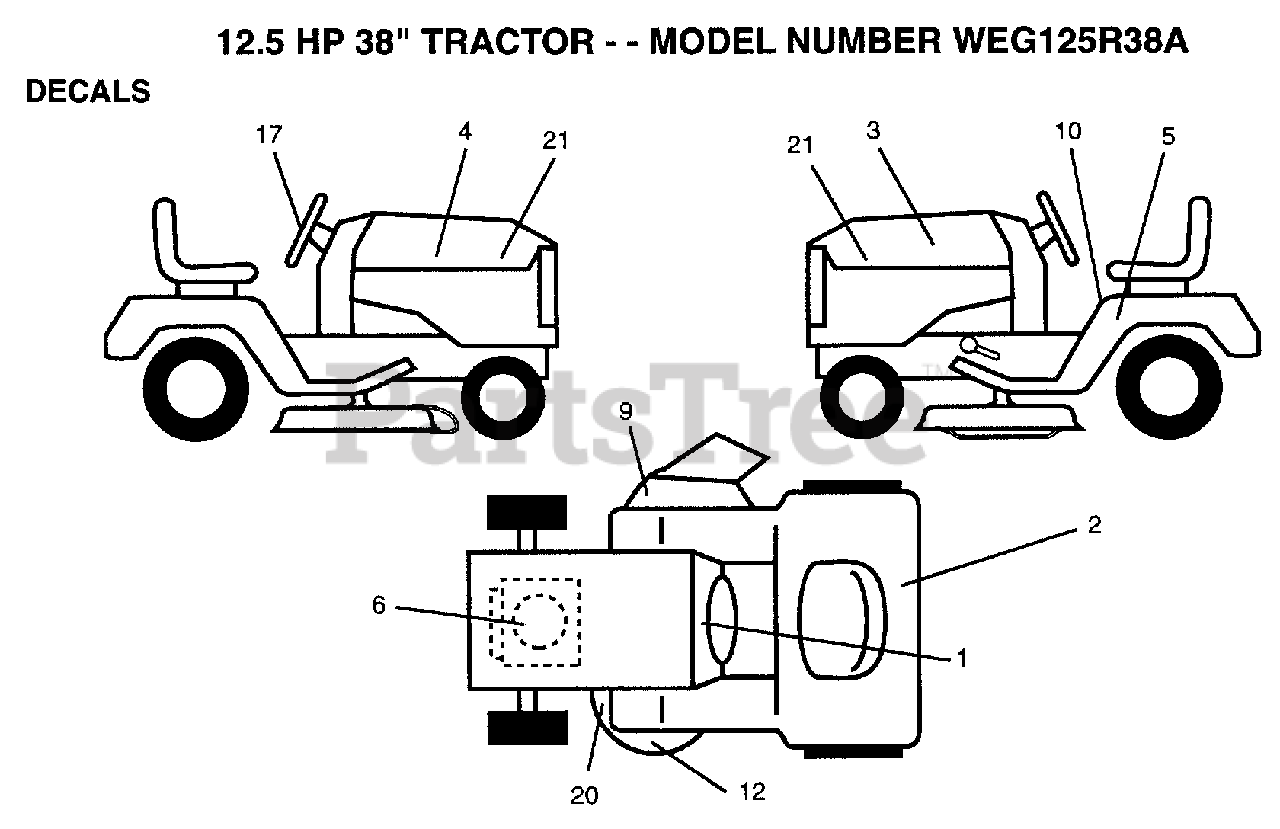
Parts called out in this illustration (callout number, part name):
1	DECAL.INST.OPER.
2	DECAL
3	DECAL.HD.LH.B&S
4	DECAL.HD.RH.B&S
5	IND HGT DECK DECA
6	DECAL.ENG.272632
9	"DECAL, WARNING"
10	DECAL CAUTION
12	DECAL.MOWER
17	DECAL.WHL.STRG.
20	DECAL
21	MANUAL.P.1A201B
